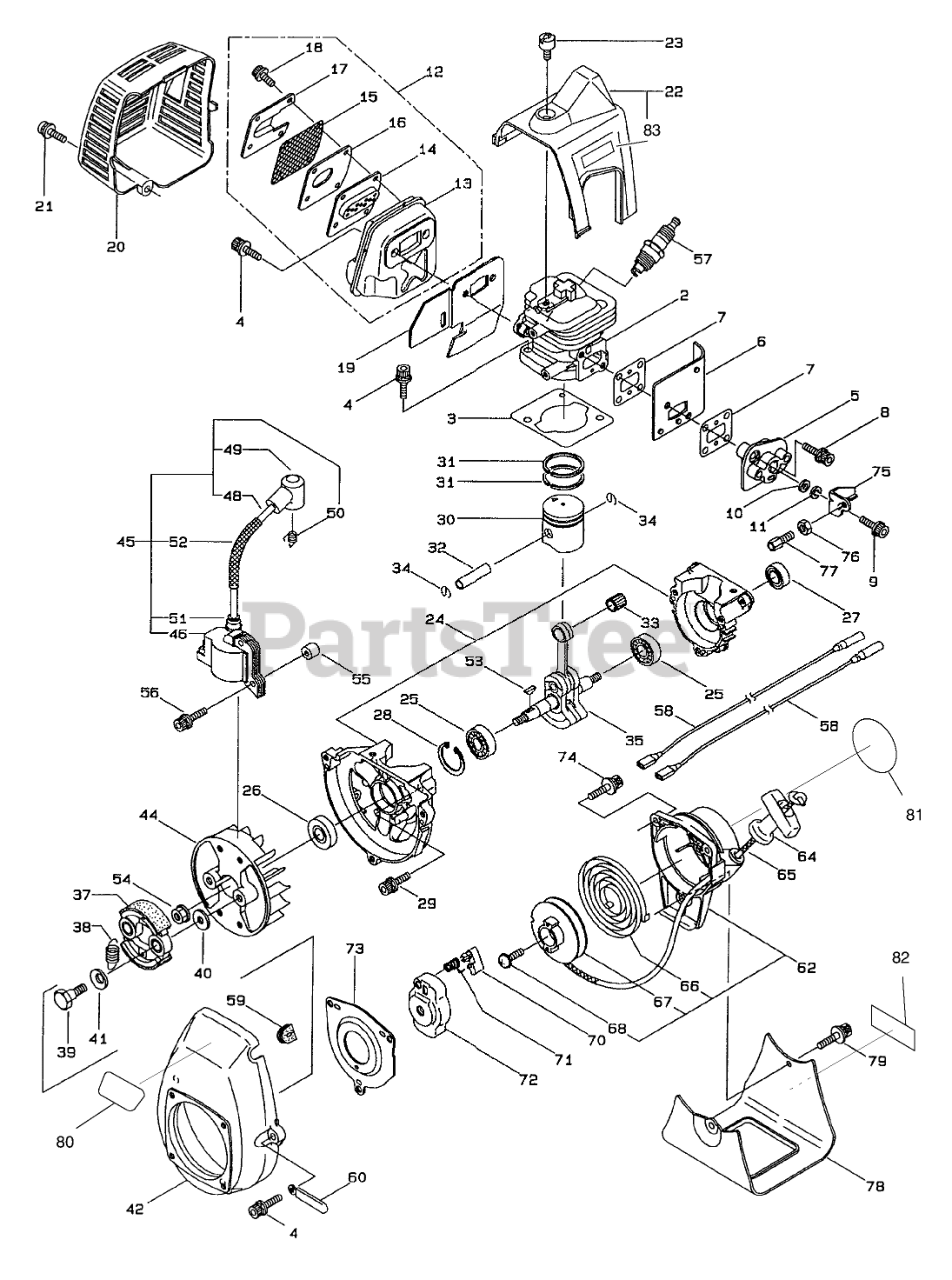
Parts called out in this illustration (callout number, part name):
2	CYLINDER
3	GASKET
5	INSULATOR
6	DUCT - AIR
7	GASKET
8	SCREW
9	CAPSCREW
10	WASHER
11	WASHER
12	Muffler Assembly (Incl. Ref. #13-18)
13	MUFFLER
14	PLATE
15	SCREEN
16	GASKET
17	OUTLET - EXHAUST
18	CAPSCREW
19	GASKET
20	COVER - MUFFLER
21	CAPSCREW
22	CYLINDER COVER W/DECAL
23	COVER - KNOB,TOP
24	CRANKCASE
25	BEARING
26	SEAL - OIL
27	SEAL - OIL
28	RING - SNAP
30	PISTON
31	RING - PISTON
32	PIN - PISTON
33	BEARING - NEEDLE
34	CIRCLIP
35	ASM - CHANKSHAFT ROD
37	SHOE - CLUTCH
38	SPRING - CLUTCH
39	BOLT - CLUTCH
40	WASHER
41	WASHER - WAVE
42	COVER - FAN
44	FAN - ROTOR
45	Ignition Coil Assembly (Incl. Ref. #46-52)
48	CABLE - IGNITION
49	CAP - PLUG
50	CONNECTOR
53	KEY - WOODRUFF
55	SPACER
57	SPARK PLUG
59	GROMMET
60	CLAMP
62	Recoil Assembly (Incl. Ref. #63-68)
64	GRIP - STARTER
65	ROPE - STARTER
66	SPRING - SPIRAL
68	SCREW
71	SPRING - RETURN
72	CASE - PAWL
73	PLATE
77	ADAPTER - SCREW
78	STAND - ENGINE
79	CAPSCREW
80	DECAL - TORO
81	LABEL - ENGINE
82	REPLACEMNT SERIAL PLT
83	DECAL - WARNING
